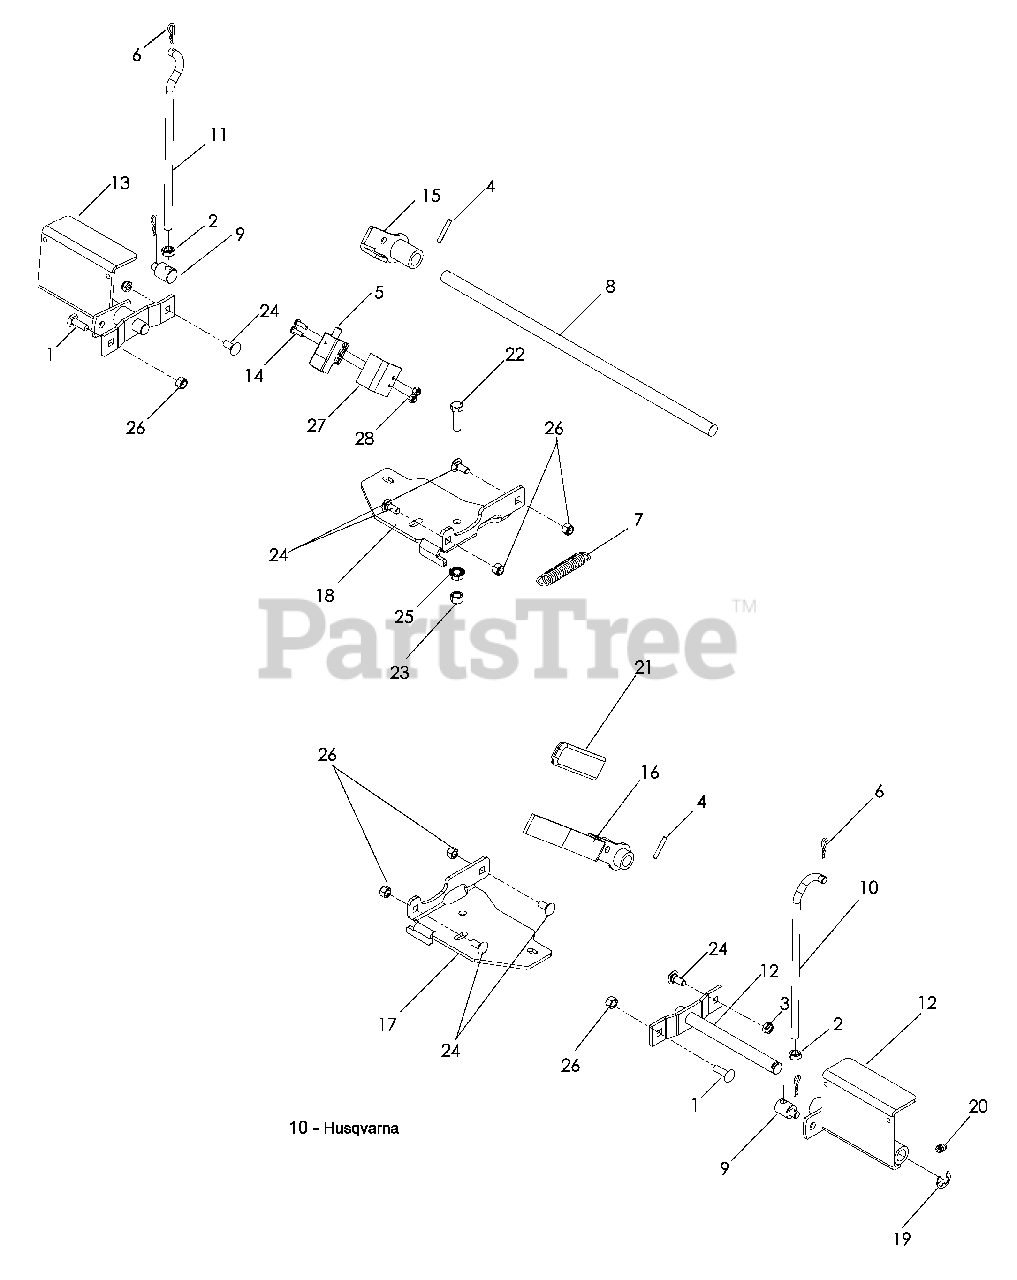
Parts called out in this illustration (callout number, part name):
1	RHSSNB 5/16-18 x 1
2	NUT 3/8-16 JAM
3	NUT 5/16-18 NYLOC
4	ROLL PIN, 3/16 x 1¼
5	BRAKE SWITCH
6	HAIR PIN COTTER
8	SHAFT, BRAKE
9	SWIVEL, BRAKE
10	ROD, BRAKE LH
11	ROD, BRAKE RH
12	BRAKE SHOE LH
13	BRAKE SHOE RH
14	SCREW #10-24 x 7/8
15	BRAKE LINK, DRILLED
16	BRAKE HANDLE DRILLED
17	BRACKET, TANK MNT LH
18	BRACKET, TANK MNT RH
19	E-RING 7/8
20	ZERK, GREASE ¼
21	GRIP, BRAKE HANDLE
22	HHB 3/8-16 x 1¼
23	NUT 3/8-16 NYLOC
24	RHSNB 5/16-18 x ¾
25	NUT 3/8-16 FLANGE
26	NUT 5/16-18 NYLOC
27	MOUNT, SWITCH
28	NUT #10-24 NYLOC
